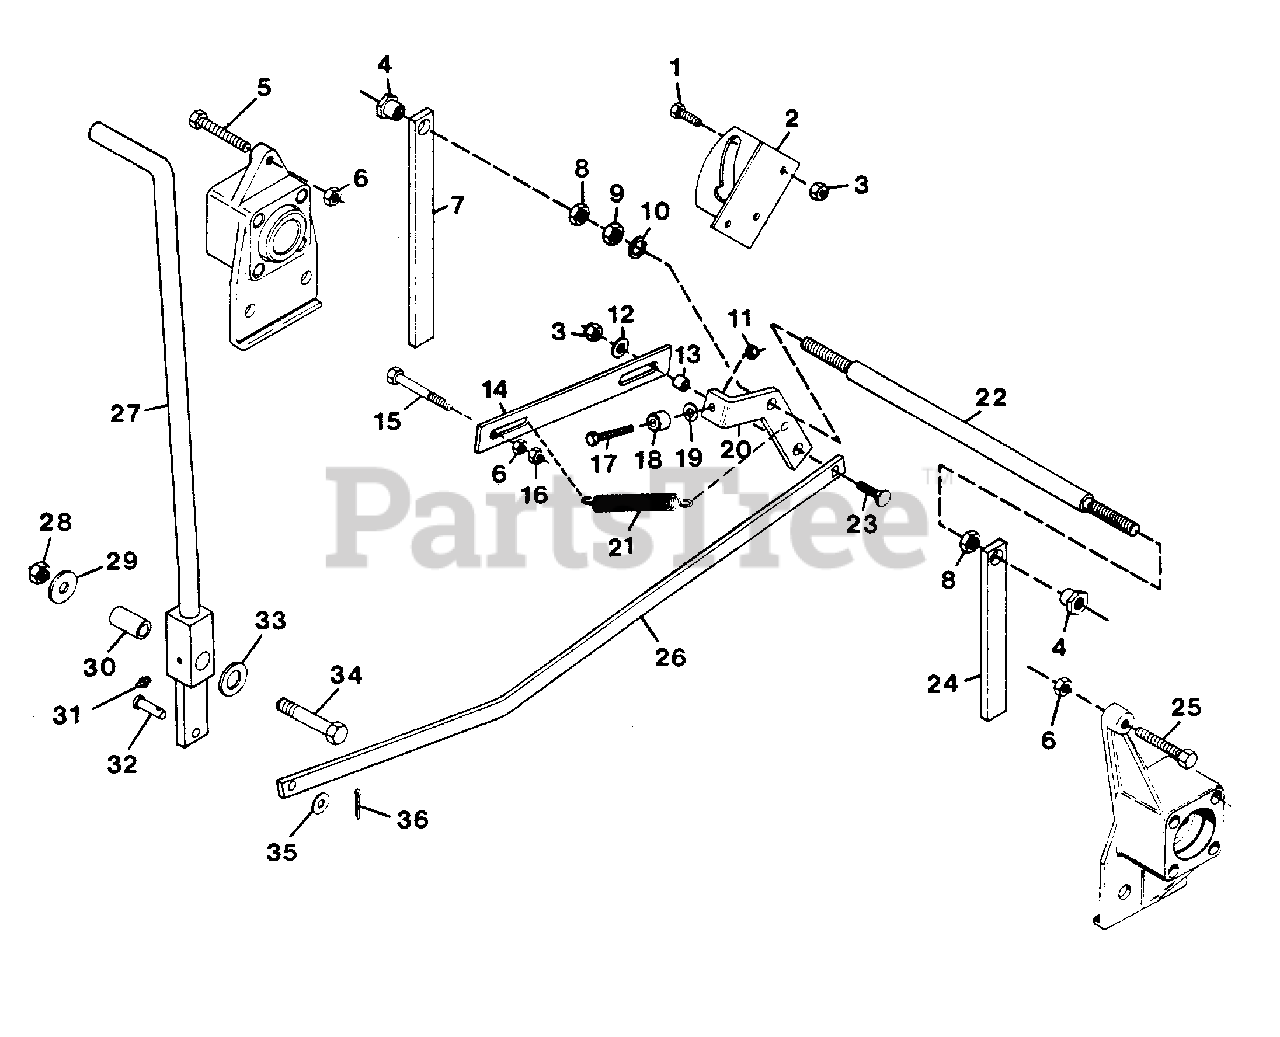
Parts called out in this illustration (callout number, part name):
1	BOLT, HEX 5/16-18X1.00
2	WELDMENT, FWD-REV ACTUATING
3	NUT, LOCK 5/16-18
4	BUSH., FLG. .500X.875X.700 STL.
5	BOLT, HEX 3/8-16X2.00 SPECIAL
6	NUT, HEX 3/8-16
7	SPRING, FWD-REV CLUTCH
8	NUT, JAM 1/2-13 HEX
9	NUT, HEX 1/2-13
10	WASHER, LOCK 1/2 SP HEAVY
11	NUT, LOCK 1/4-28
12	WASHER, FLAT .313X.875X.065
13	BUSH., STL. .328X.500X.500 STL.
14	STRAP, NEUTRAL DETENT
15	BOLT, HEX 3/8-16X3.00
16	NUT, LOCK 3/8-16
17	BOLT, HEX 1/4-28X1.38 GR.8
18	ROLLER, CLUTCH CAM
19	WASHER, FLAT .281X.625X.065
20	ARM, FWD-REV CLUTCH ROLL
21	SPRING, NEUTRAL DETENT
22	ROD, FWD-REV SLIDE
23	BOLT, 5/16-18X1.25 RD HD SQ NK
24	SPRING, REVERSE CLUTCH
25	BOLT, HEX 3/8-16X2.50
26	LINK, FWD-REV SHIFTER
27	WELDMENT, FWD-REV LEVER
28	NUT, LOCK 1/2-13
29	WASHER, FLAT .563X1.375X.109
30	BUSH., ST. .515X.748X1.44 STL.
31	FITTING, LUBE 1/4-28
32	PIN, CLEVIS .375X.948
33	WASHER, FLAT .812X1.496X.134
34	BOLT, HEX 1/2-13X2.75
35	WASHER, FLAT .406X.812X.065
36	PIN, COTTER .09X.75
